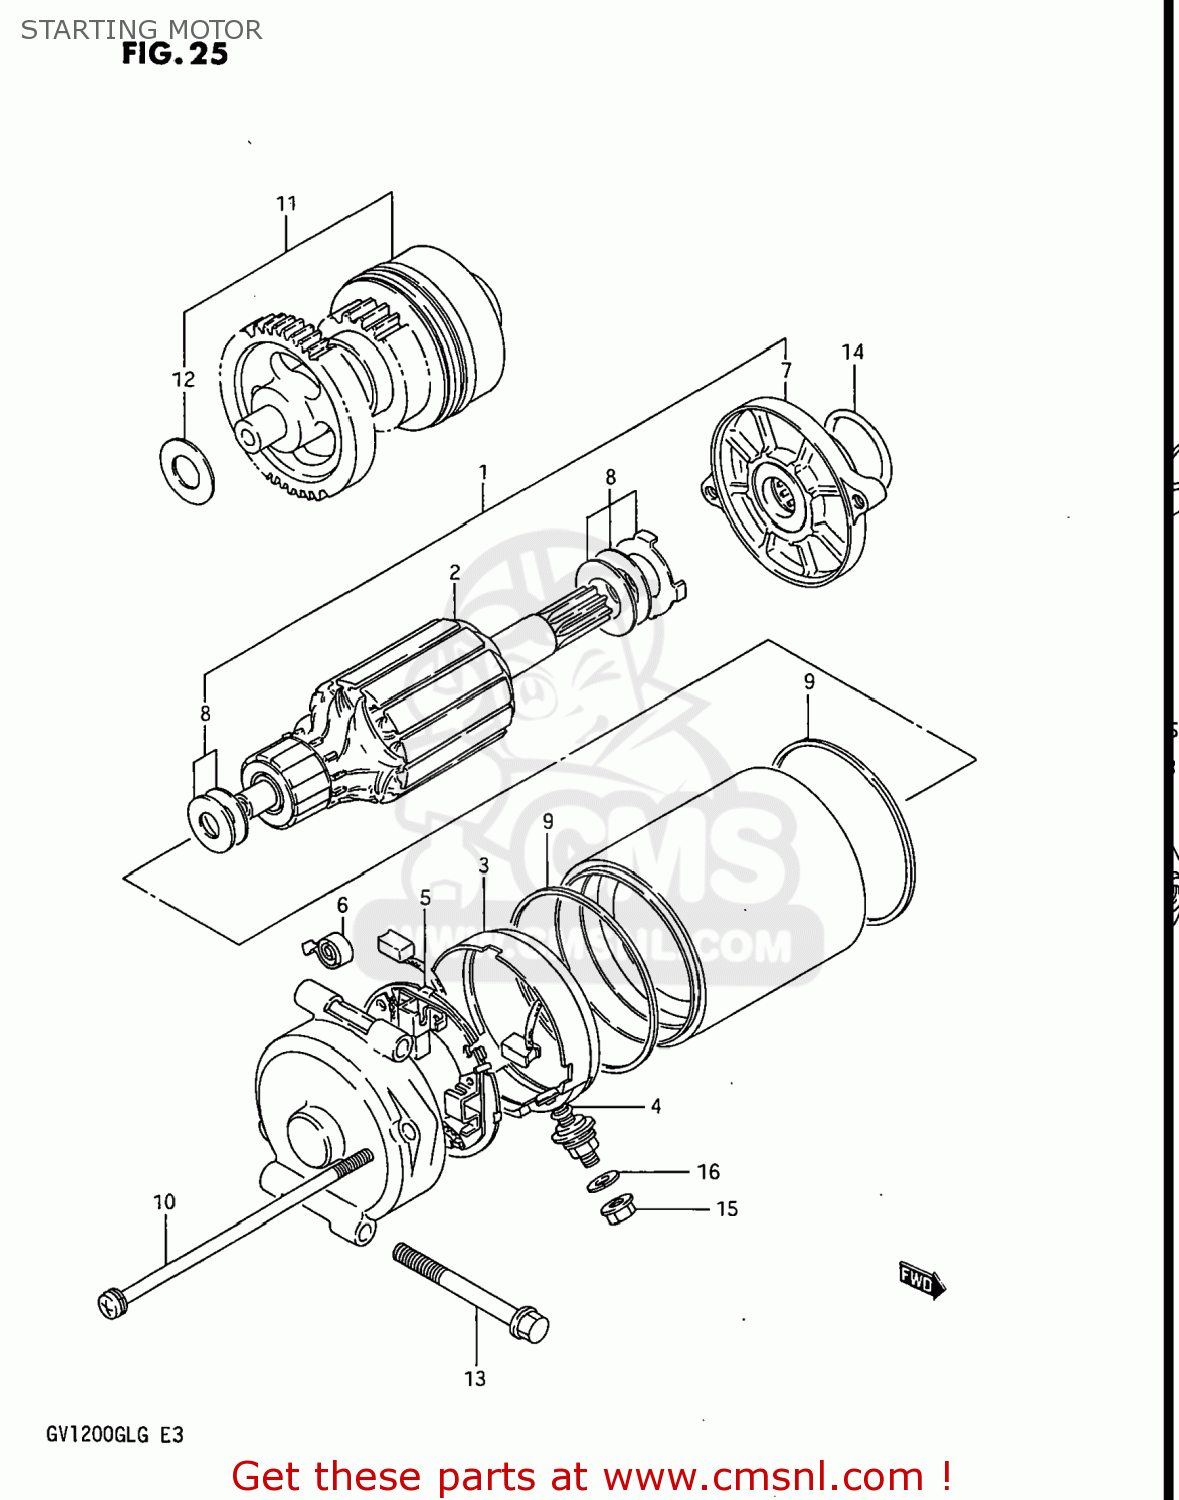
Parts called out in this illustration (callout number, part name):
1	MOTOR ASSEMBLY,STARTING
2	ARMATURE
3	BRUSH TERMINAL SET
4	O RING
5	HOLDER,BRUSH
6	SPRING,BRUSH
7	BRACKET SET,STARTING MOTOR
8	SHIM SET,STARTING MOTOR
9	SEAL,RING
10	BOLT
11	PINION ASSEMBLY,STARTING MOTOR
12	SHIM
13	BOLT (6X60)
14	O RING(D:3,ID:24.5)
15	NUT
16	WASHER,LOCK
